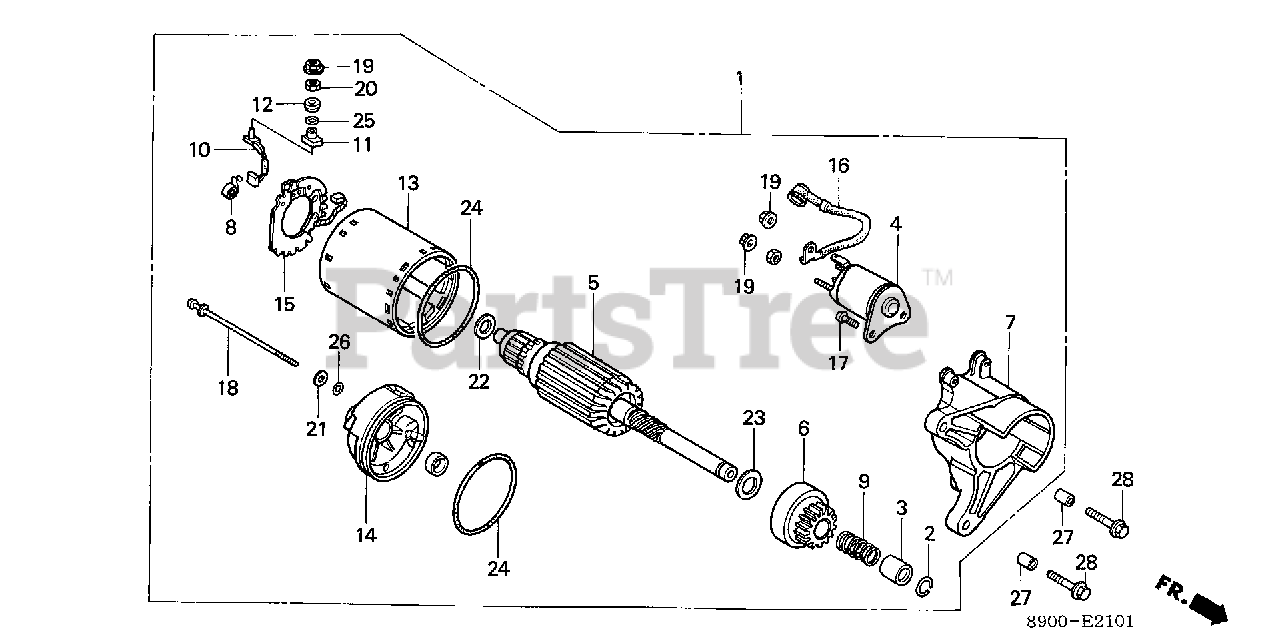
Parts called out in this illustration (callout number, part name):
1	STARTER MOTOR ASSY.
2	RING, SNAP
3	COLLAR, CLUTCH STOP
4	CONTACTOR ASSY.
5	ARMATURE
6	CLUTCH ASSY., OVERRUNNING
7	HOUSING, DRIVE SIDE
8	SPRING, BRUSH
9	SPRING
10	BRUSH
11	BUSH, INSULATION
12	BUSH, INSULATION (NOT AVAILABLE)
12	BUSH, INSULATION
13	YOKE (NOT AVAILABLE)
13	YOKE
14	FRAME, STARTER END
15	PLATE, BRUSH HOLDER
16	WIRE, WATER COVER (NOT AVAILABLE)
16	WIRE, WATER COVER
17	BOLT
17	SCREW-WASHER (5X14)
18	BOLT, THROUGH (NOT AVAILABLE)
18	BOLT, THROUGH
19	NUT
20	NUT
21	WASHER, STEEL PLATE (NOT AVAILABLE)
22	WASHER
23	WASHER
24	O-RING
25	O-RING
26	O-RING
27	PIN, DOWEL (10X16)
28	BOLT, FLANGE (8X35)
